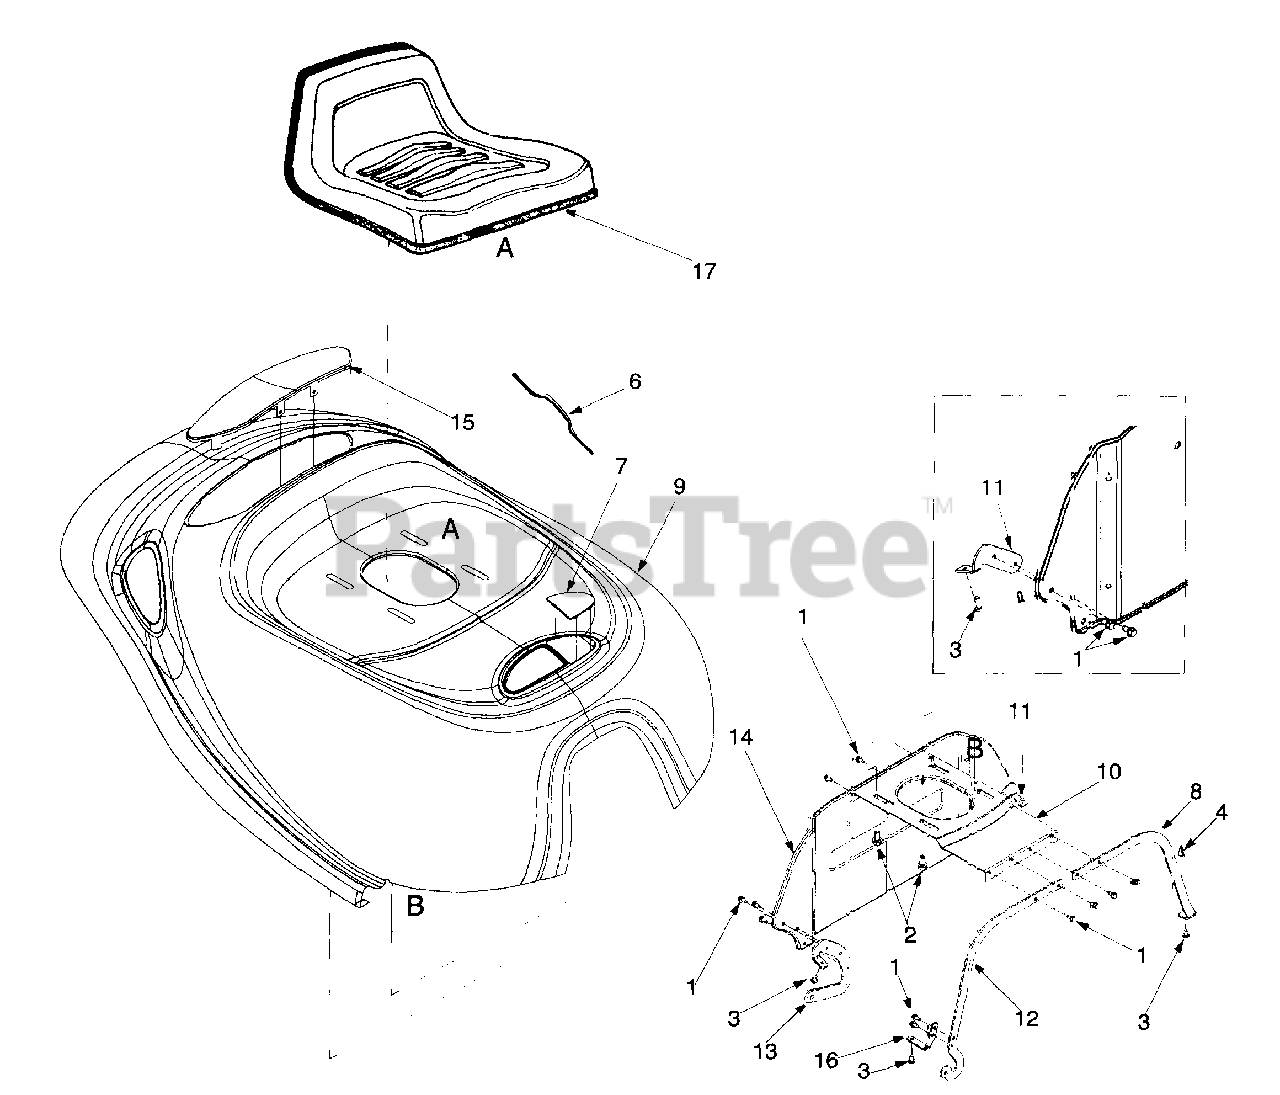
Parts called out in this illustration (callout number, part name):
1	Hex Hd. TT Screw 1/4-20 x 05
2	Hex Washer Hd. TT Screw 3/8-16 x 0.62
3	Torx Head AB screw 1/4-14 x 0.625
4	Rod End Grip
6	Trim Strip
7	Grass Bag Lens
